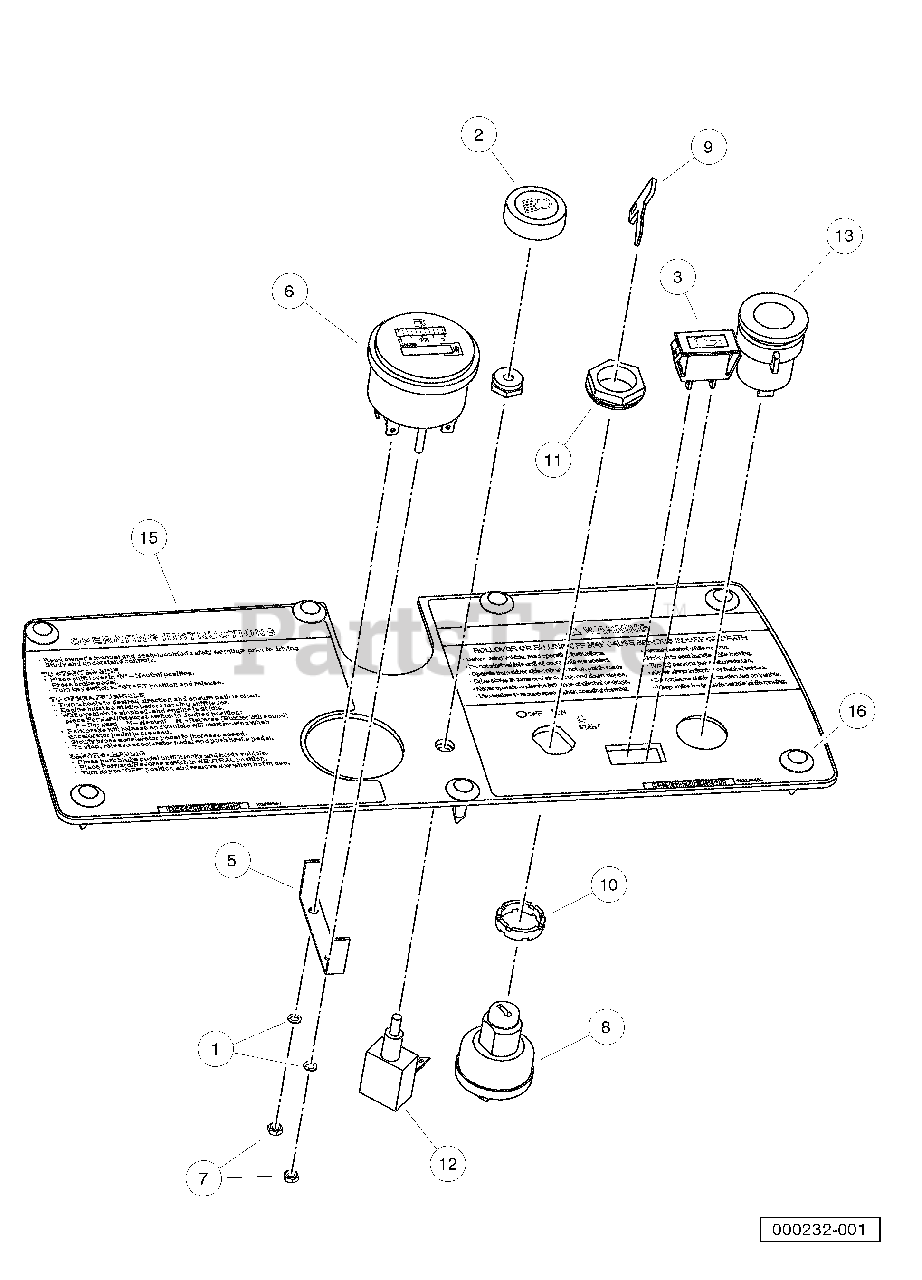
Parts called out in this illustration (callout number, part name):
2	Knob, Light Switch
3	Light, Oil
4	Gauge, Fuel/Hour, with Bracket
5	Bracket, Fuel Gauge/Hour Meter
6	Gauge, Fuel/Hour
7	Nut, IVI4-0.7
8	Key Switch 12v Key Start
10	Spacer, Keyswitch
11	Nut, Key Switch
12	Switch, Light
13	Receptacle, Accessory
14	Panel, Instrument
15	Panel, Instrument
16	Rivet, Removable, Tuflok 1/4"
